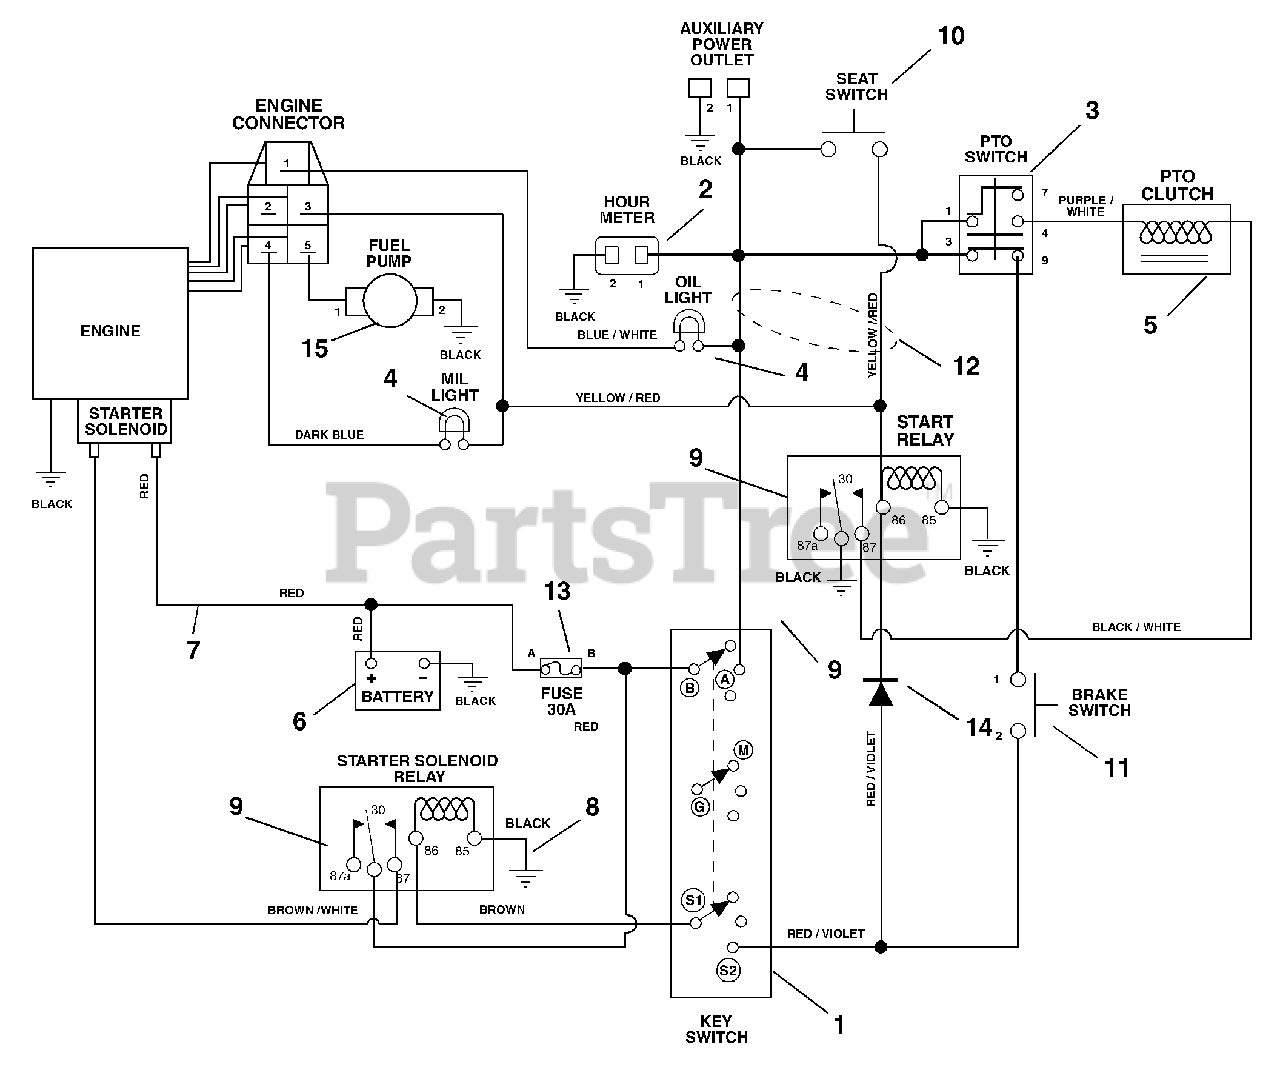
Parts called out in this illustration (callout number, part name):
1	Key Switch
2	Hour Meter
3	Switch-Clutch With Retainer Ring
4	Light-Indicator
5	Electric Clutch
6	Battery with Tube
7	Cable-Battery To Solenoid
8	Ground Cable
9	Relay
10	Seat Switch
11	Switch-Single Pole
12	Harness-EFI Wiring
13	Fuse, 30 Amp
14	Molded Diode Plug-Black 1-Amp
15	Pump, EFI Fuel
